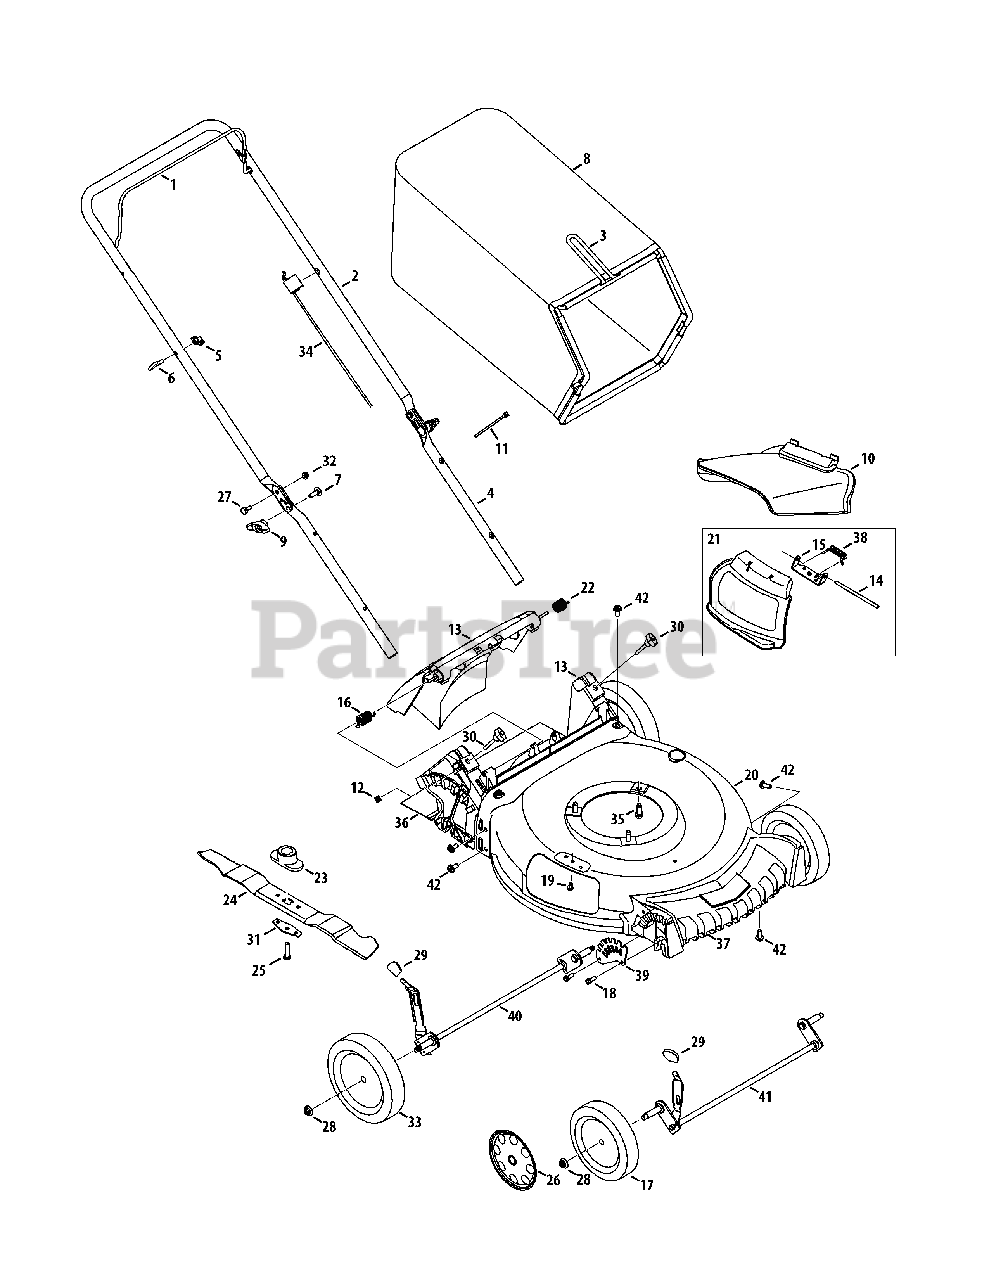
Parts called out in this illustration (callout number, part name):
1	Blade Control
2	Upper Handle
3	Grass Catcher Frame
4	Lower Handle
6	Rope Guide
7	Carriage Screw ,5/16-18
8	Grass Bag
10	Side Chute
10	Side Chute w/Flap
11	Cable Tie
12	Nut, Sq., 1/4-20
13	Rear Discharge Door Assembly
13	Rear Discharge Door Assembly - (Lowes 766)
15	Chute Deflector Bracket
16	Torsion Spring - RH
17	Front Wheel
18	Screw, 1/4-15 x .750
19	Screw, 1/4-20 x .500
20	Deck , 21"
21	Hinged Mulch Plug Assembly
22	Torsion Spring - LH
23	Blade Adapter
24	Mulching Blade
25	Screw , 3/8-24 x 1.50
27	Sldr. Screw, .375 x .126 x 1/4-20
28	Flange Lock Nut, 3/8-16
29	Adjustment Lever Knob
30	Wing Nut
31	Blade Bell Support
32	Nut, Flange Lock, 1/4-20
33	Rear Wheel
34	Control Cable
35	TT Sems Screw, 3/8-16 x 1.0
36	Trail Shield
37	Front Cover
38	Torsion Spring
39	Front Height Adjuster Plate
40	Rear Axle Assembly
41	Front Axle Assembly
42	Screw, 5/16-14 x .750
